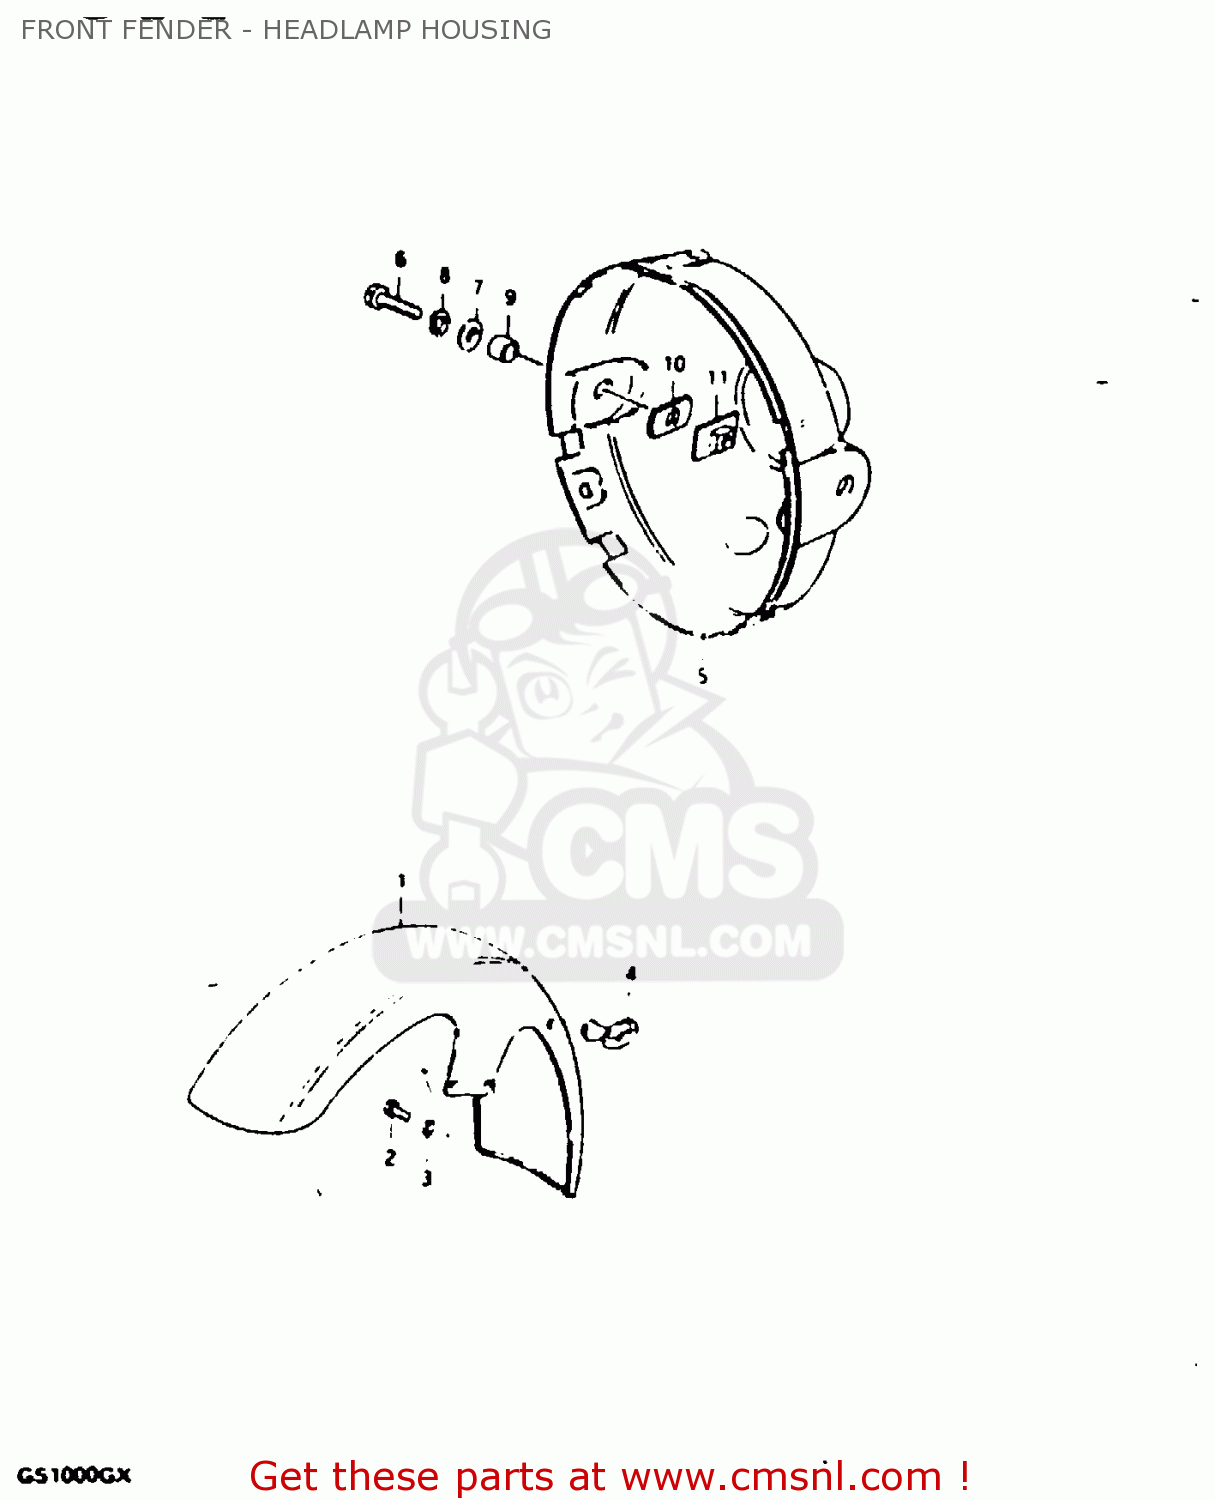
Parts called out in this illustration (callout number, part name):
1	FENDER,FR
2	BOLT
3	LOCK WASHER
4	GUIDE,CABLE
5	HOUSING,HEADLAMP(BLACK)
6	BOLT
7	WASHER
8	LOCK WASHER
9	SPACER (8.8X12X7)
10	CUSHION
11	PLATE,HEADLAMP HOUSING
